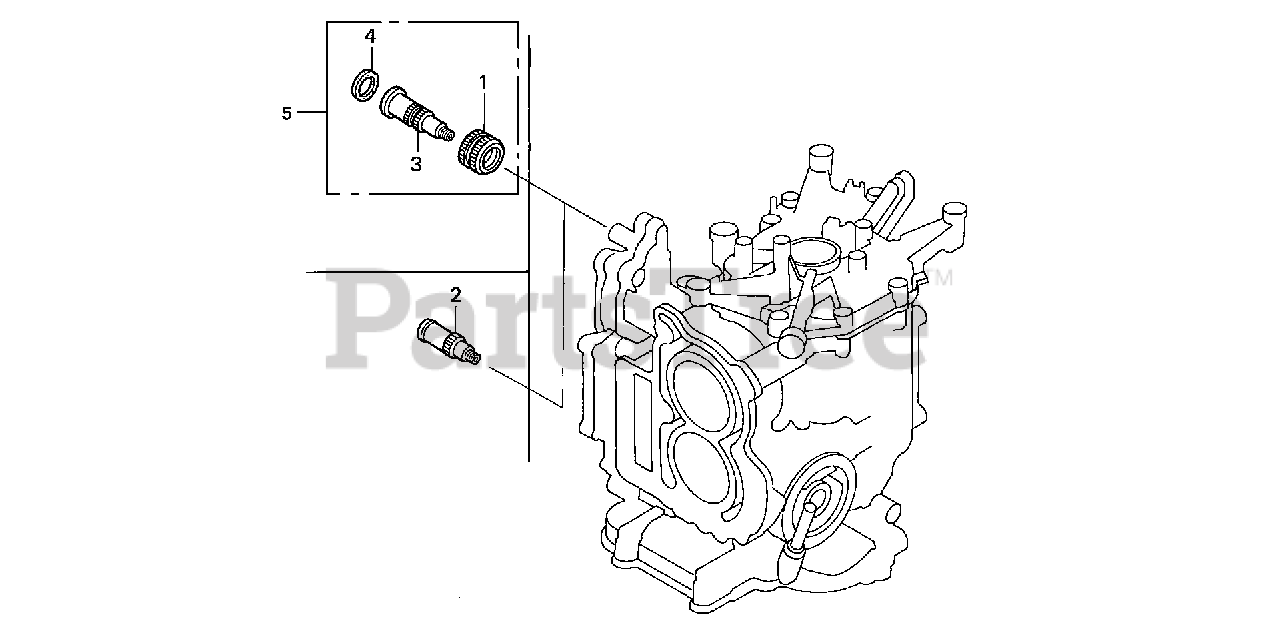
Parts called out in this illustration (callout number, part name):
1	NUT, WATER MOUTH
2	JOINT, WATER HOSE
3	JOINT, WATER HOSE
4	SEAT, WATER MOUTH
5	JOINT KIT, WATER HOSE
